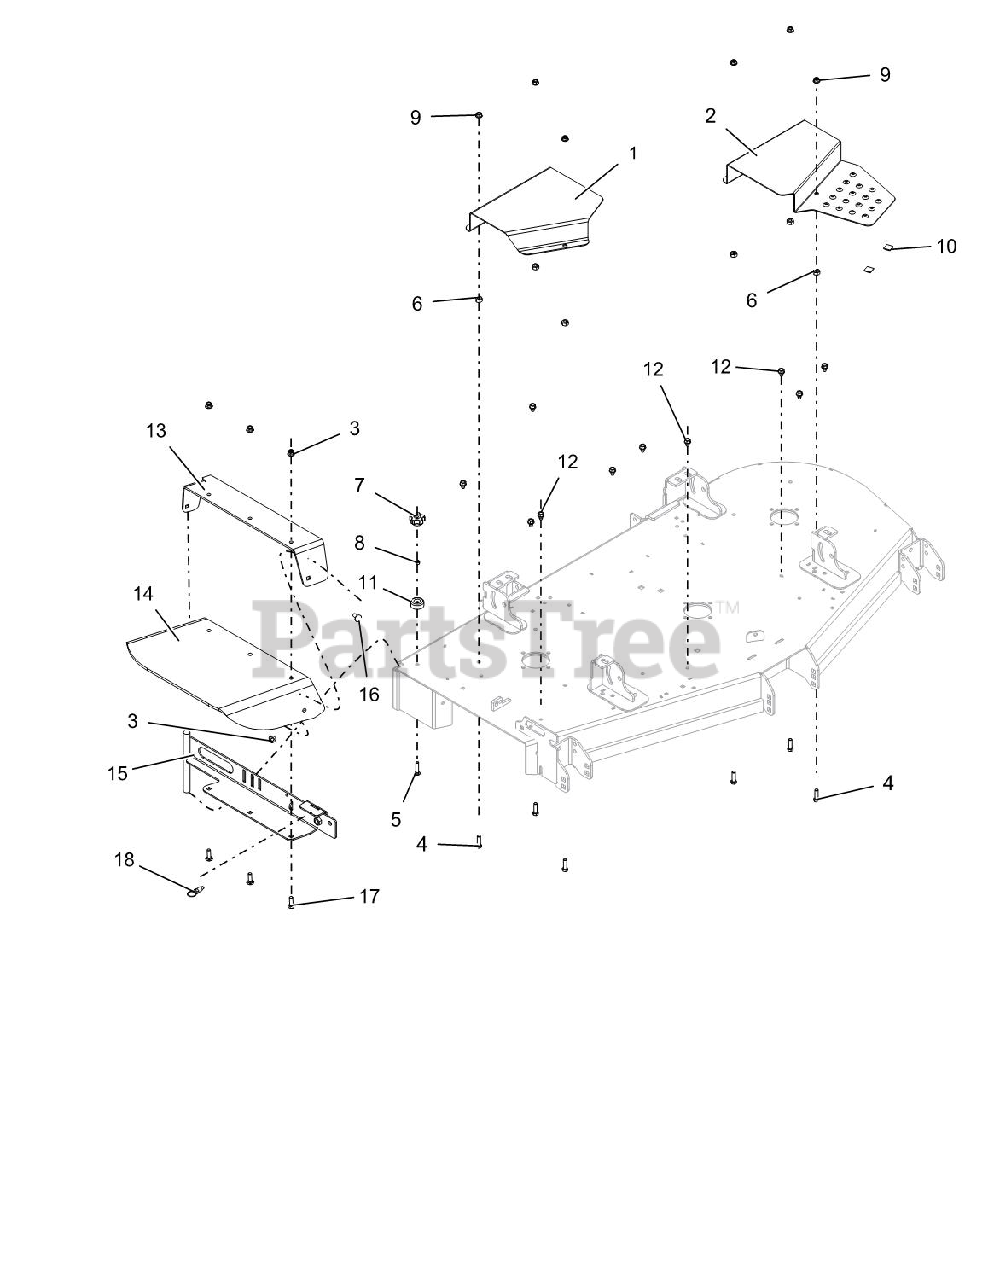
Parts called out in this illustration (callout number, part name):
1	60"-66" RH DECK BELT GUARD-RED
2	GUARD-60" LH DECK BELT W/STEP
3	NUT-LK-NYL-FLG .38-16 YWZC
4	BLT-HEX .38-16X1.25 GR5 YWZC
5	BLT-RDHDSQNK .31-18X1.50 G5YZ
6	NUT-HEAVY HEX .38-16 YWZC
7	KNOB-CLAMPING, .312-18 NYLOC
8	NUT-LK-CTR .31-18 YWZC
9	NUT-SPNLK-FLG .375-16 YWZC
11	BUMPER,RECESSED1.50X.63 W/.31
12	SCR-TAP .38-16X.50 HWH TR YWZ
13	DISCH CHUTE SUPPORT W/DECAL
14	CHUTE, RUBBER DISCHARGE
15	WMT, 52"-60" DISCH CHUTE MTG
16	BLT-RDHDSQNK .38-16X1.00 G5YZ
17	BLT-RDHDSQNK .38-16X1.25 G5YZ
18	PULL PIN,.50-13THDX.310 PLNGR
